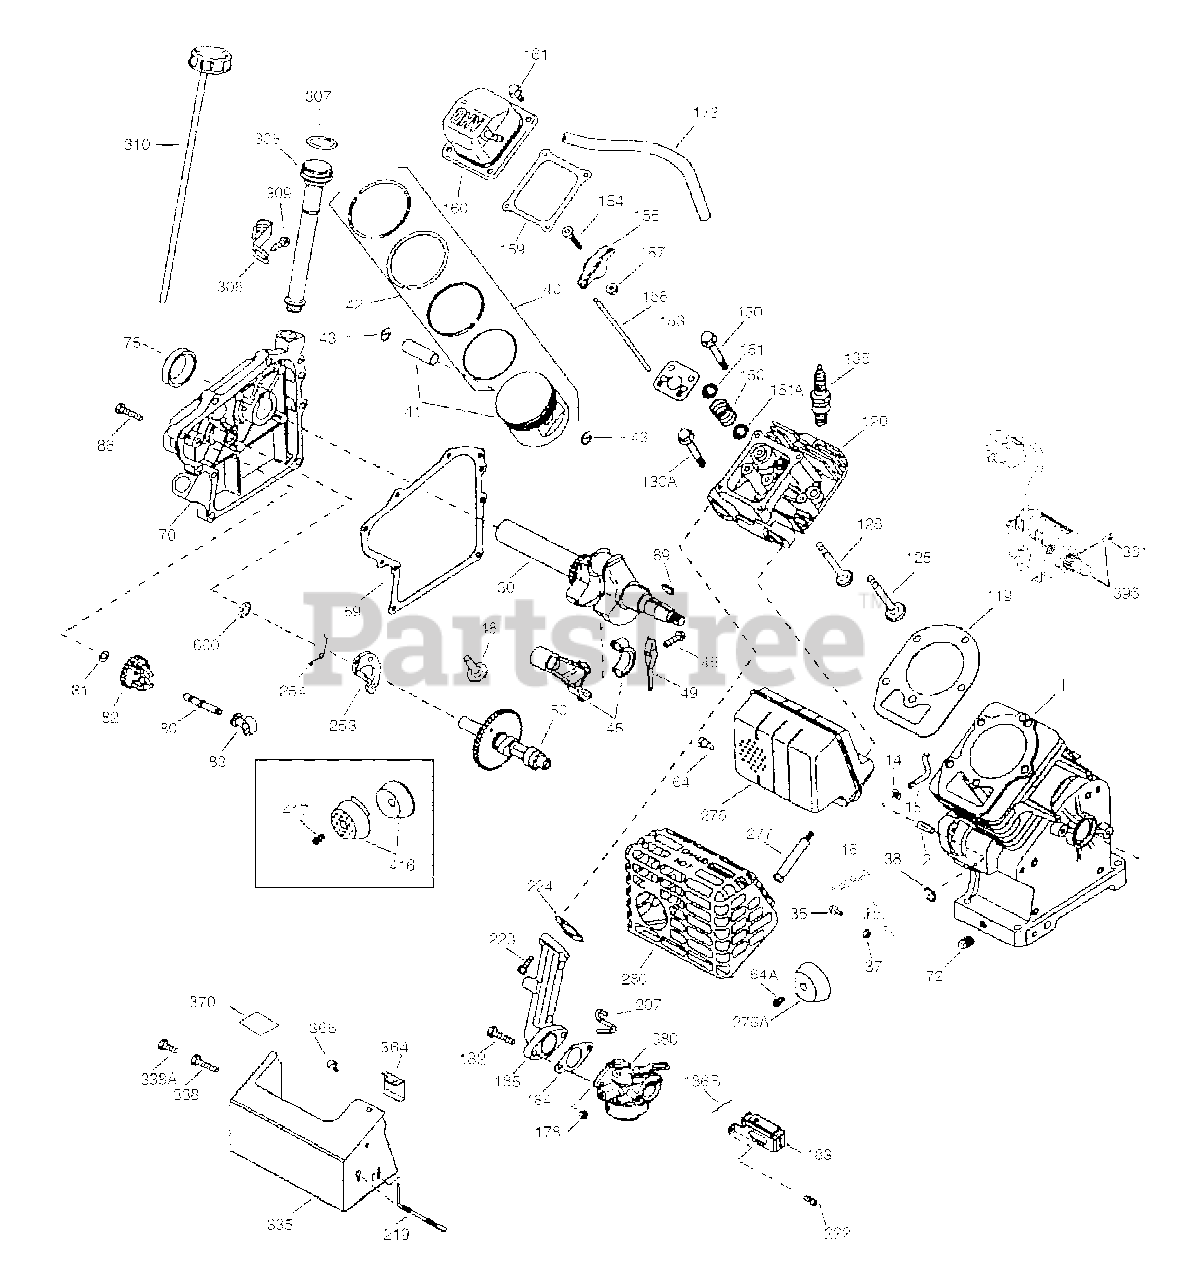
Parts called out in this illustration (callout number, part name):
1	Cylinder
2	Dowel Pin
15	Governor Rod
16	Governor Lever
30	Crankshaft
35	Screw, 10-32 x 63/64"
37	Lock Nut, 10-32
38	Retaining Ring
40	Piston, Pin & Ring Set (Std.)
40	Piston, Pin & Ring Set (.010" OS)
41	Piston & Pin Ass'y (Std.)
41	Piston & Pin Ass'y (.010" OS)
42	Ring Set (Std.)
42	Ring Set (.010" OS)
43	Piston Pin Retaining Ring
45	Connecting Rod Ass'y
46	Connecting Rod Bolt
48	Valve Lifter
49	Oil Dipper
50	Camshaft
64	Screw, 1/4-20 x 27/32"
64A	Screw, 8-32 x 3/8"
69	Cylinder Cover Gasket
70	Cylinder Cover
80	Governor Shaft
82	Governor Gear Ass'y
83	Governor Spool
86	Screw, 1/4-20 x 1-1/4"
89	Flywheel Key
119	Cylinder Head Gasket
120	Cylinder Head
125	Exhaust Valve (Std.)
125	Exhaust Valve (1/32" OS)
126	Intake Valve (Std.)
130	Screw, 5/16-18 x 1-1/2"
130A	Screw, 5/16-18 x 2-41/64"
135	Resistor Spark Plug (RN4C)
150	Valve Spring
151	Valve Spring Cap
151A	Intake Valve Seal
153	Push Rod Guide
154	Rocker Arm Stud
155	Rocker Arm
157	Nut, 1/4-28
159	Rocker Arm Cover Gasket
160	Rocker Arm Cover
173	Breather Tube
178	Nut, 1/4-20
182	Screw, 1/4-20 x 1"
183	Choke Bracket
184	Carburetor To Intake Pipe Gasket
185	Intake Pipe
186B	Choke Spring
207	Throttle Link
219	Choke Rod
222	Screw, 10-32 x 1/2"
223	Screw, 1/4-20 x 1"
224	Intake Pipe Gasket
253	Compression Release Weight
254	Compression Release Spring
275	Muffler
275A	Exhaust Deflector(Black)
277	Screw, 1/4-20 x 2-9/32"
305	Oil Fill Tube
308	Fill Tube Clip
309	Screw, 1/4-20 x 31/64"
335	Carburetor Cover
338	Screw, 10-32 x 1/2"
338A	Screw, 10-32 x 3/8"
361	Screw, T-30, 1/4-20 x 15/32"
364	Carburetor Cover Bracket
365	Screw, 10-32 x 1/2"
370I	Warning Decal
380	Carburetor
396	Electric Starter Motor (120V)
416	Spark Arrestor Kit
417	Screw, 10-32 x 1/2"
